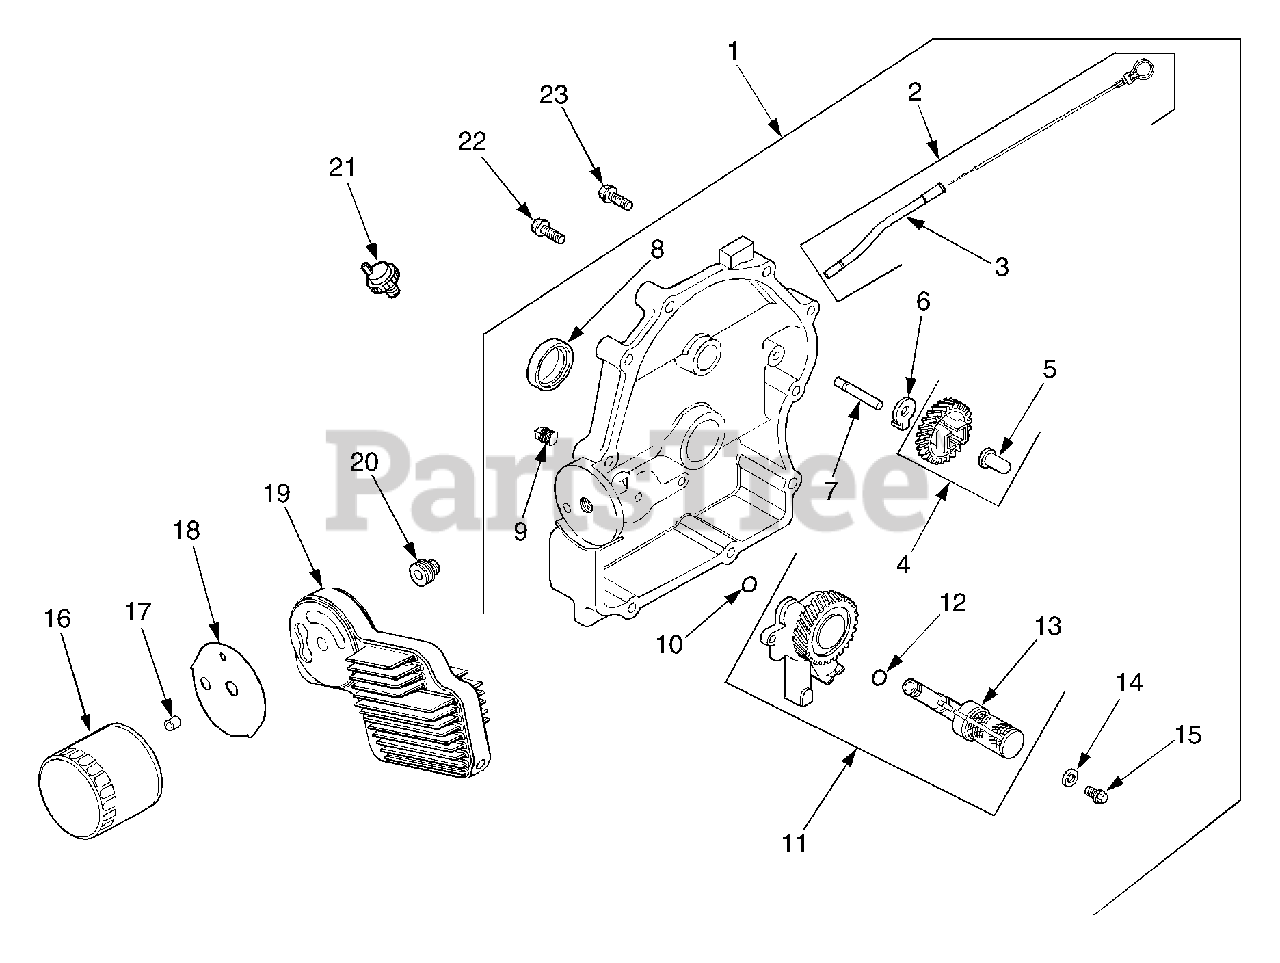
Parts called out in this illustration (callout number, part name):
1	Plate, Closure Assembly
3	Tube, Dipstick
4	Kit, Governor Gear
5	Pin, Governor Regulating
7	Shaft, Governor Gear
8	Seal, Oil (PTO End)
9	Plug, Pipe 1/8"
11	Oil Pump Assembly
12	O-Ring, Oil Pick-Up
13	Pick-Up, Oil
14	Washer, Plain
15	Screw, Hex Flange M6 x 1 x 25
16	Filter, Oil
17	Pin, Locating
18	Gasket, Adapter
20	Nipple, Oil Filter
21	Switch, Pressure
22	Screw, Hex Flange M8 x 1.25 x 45
23	Screw, Hex Flange M8 x 1.25 x 45
